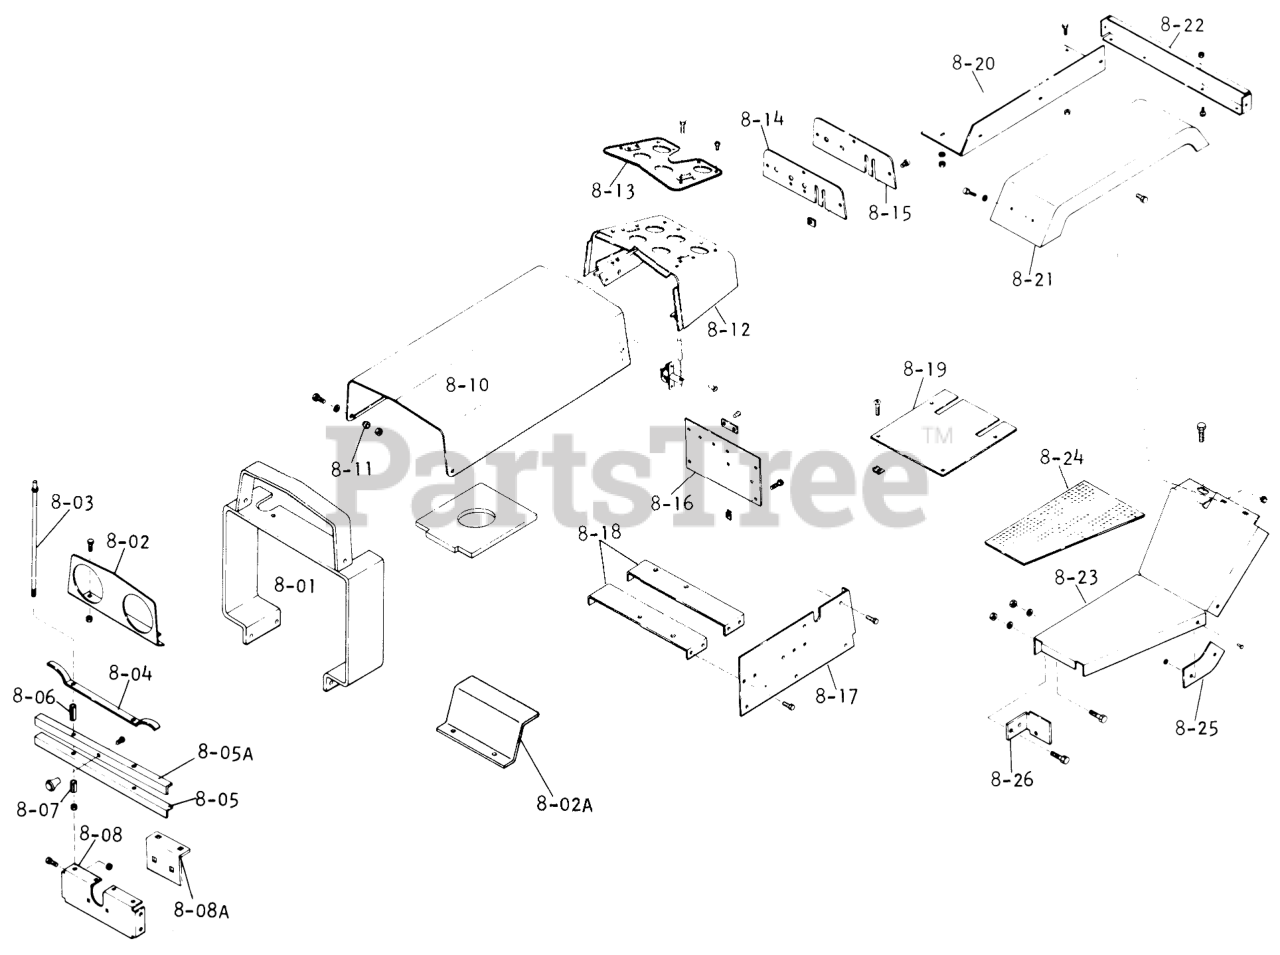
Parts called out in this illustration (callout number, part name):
8-01	Asy-Grille Shroud
8-02	Light Bracket
8-02A	Cotter Pin
8-03	ROD-GRILLE
8-04	SPRING GRILLE
8-05	Grille
8-05A	Angle-Grille
8-06	Spacer
8-07	Spacer
8-08	Cover-Front
8-08A	Cover
8-10	Hood Assembly
8-11	Bushing
8-13	Left Differential Gear
8-14	Idler Shaft
8-15	Plate-Instrument Instruction
8-16	Washer 1/4
8-17	Panel-Console RH
8-18	Battery Support
8-19	Access Cover Plate
8-20	Plate-Fender RH
8-21	Fender-Right and Left
8-22	Channel
8-23	Footrest-R.H.
8-24	Footrest Mat RH
8-25	Filler Plate
8-26	Bracket
